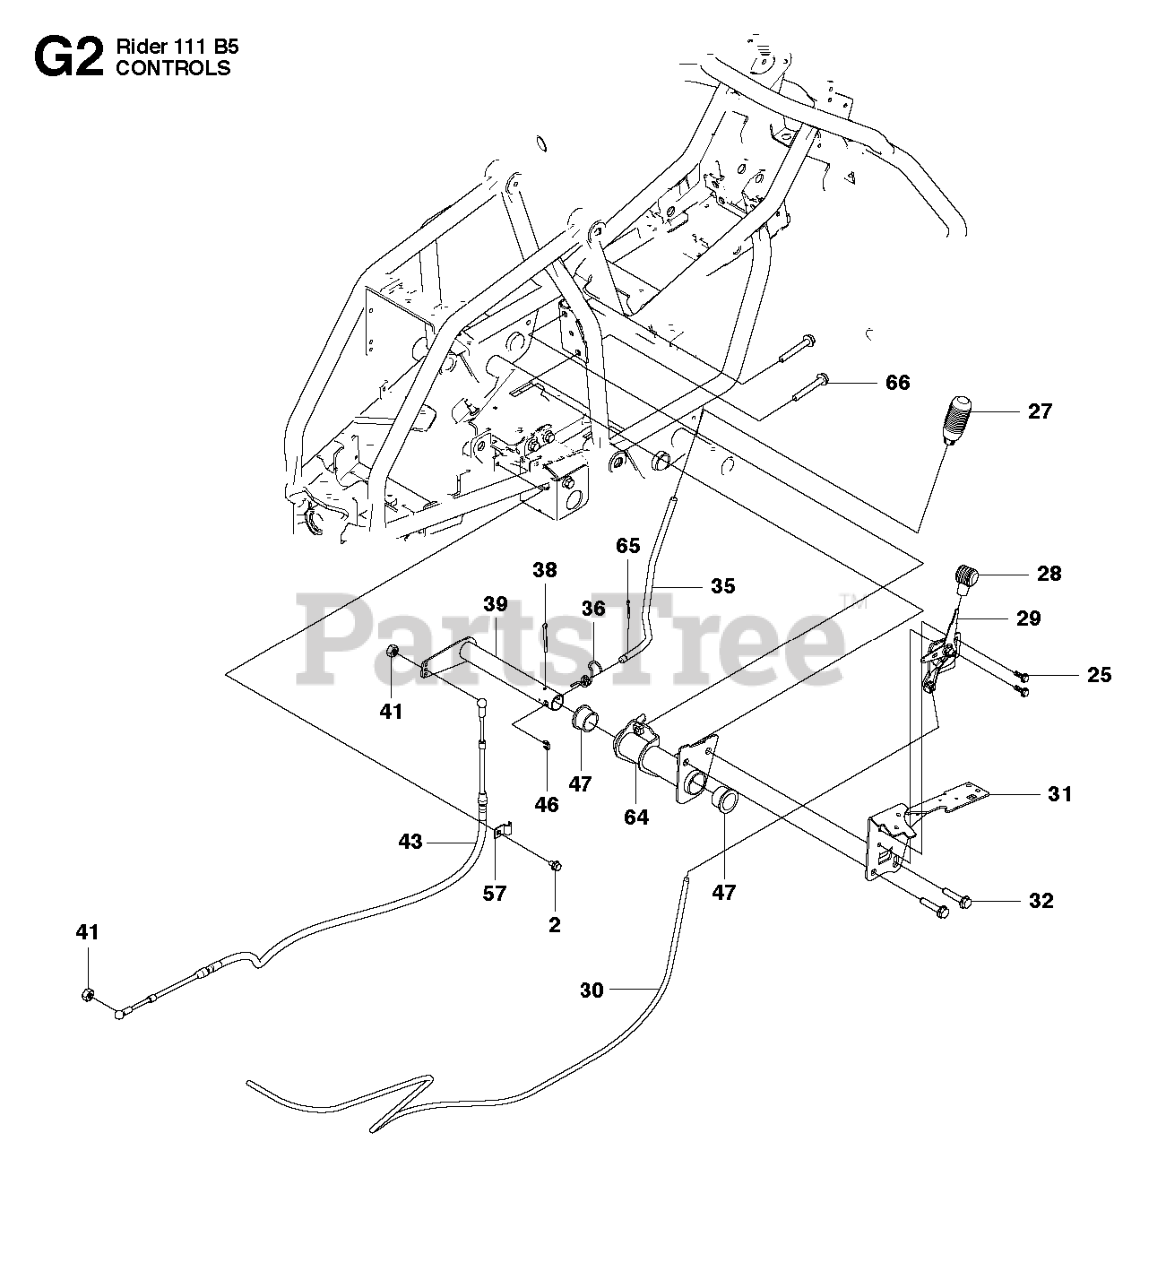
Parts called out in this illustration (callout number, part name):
27	GEAR STICK KNOB
29	THROTTLE CONTROL
41	LOCKNUT M5
46	Retaining Ring
47	BEARING FLANGE
65	Cotter Pin
66	SCREW
